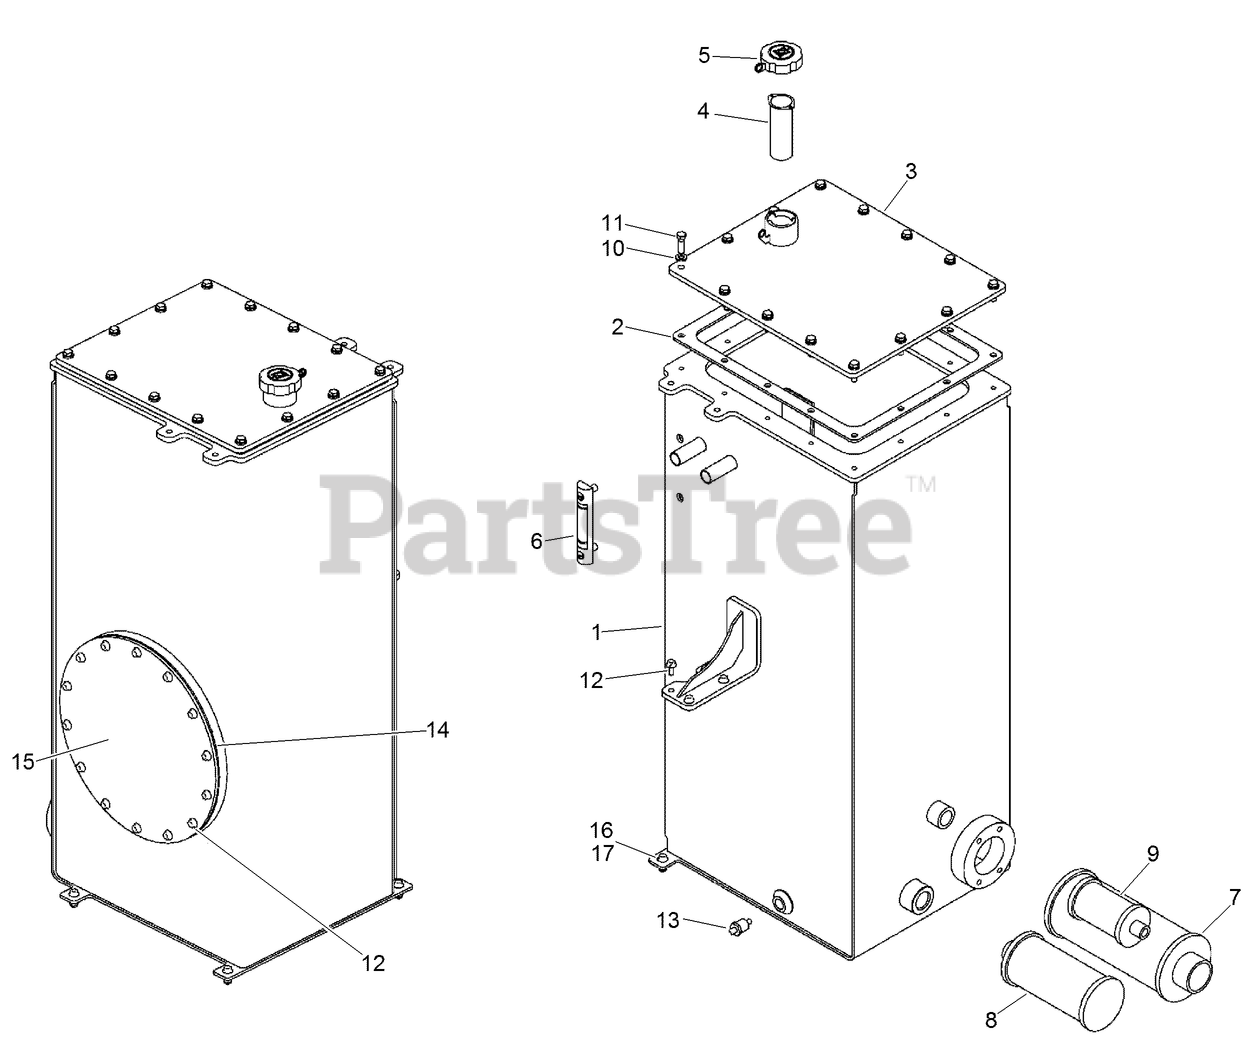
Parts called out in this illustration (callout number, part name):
1	TANK-HYD
2	GASKET-COVER
3	WELDMENT - Cover, Hydraulic Tank
4	FILTER-SCREEN, MESH
5	CAP-HYD FLUID (W/ LOCK)
6	GAUGE-SIGHT
7	STRAINER-NIPPLE
8	STRAINER-SUCTION
9	STRAINER-NIPPLE
10	WASHER - 0.406 x 0.750 x 0.119 in CST ZND
11	BOLT
12	SCREW, METRIC FLANGE w/BODY - M8 x 20
13	SENDER-TEMPERATURE, WATER
14	GASKET-HYD, TANK
15	GASKET - Hydraulic Tank
16	SCREW-HH
17	NUT-TORQUE, PREVAILING
